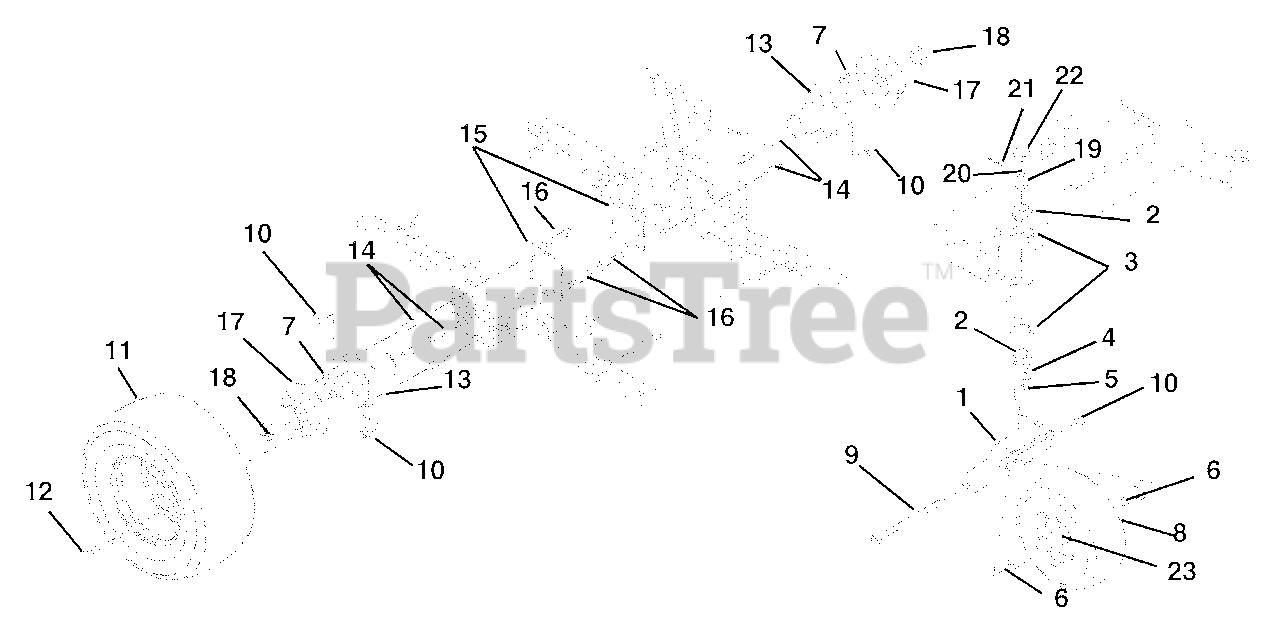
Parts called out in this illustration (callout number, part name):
1	FORK - BLACK
2	BRG, CONE W/ GREASE
3	BRG-CUP1.980X.420
4	BEARING SEAL 1.5 X 2 X .18
5	SPACER 1.005X1.5075X.375
6	SPACER, WHEEL
7	KEY-WDRF .31X1.00 SFT #B
8	WHEEL/TIRE ASM
9	@BLT-HEX .50-13X9.00 GR5 YWZC
10	@NUT-LK-TOP-FLG .50-13 YWZC
11	TIRE/WHEEL ASSY, 23X10.50-12
12	BLT, LUG .50-20 X 1.38
13	WHEEL MOTOR, MB15
14	BSHG-SLV .513X.748X2.129
15	PLATE, MOTOR SUPPORT
16	BOLT, WHEEL MOTOR 1/2-13X5.00
17	HUB & DISK (PARK) 8" 1/2 HOLE
18	NUT-LK-JAM-PTCH 1.00-20
19	WSHR-FL-STL.755X1.375X.062YWZC
20	NUT, SLOTTED .75-16
21	@PIN-CTR .16X1.00 EXTPRSQCT YZ
22	CAP,DUST
23	BRG, 25MM ID X 52MM OD X 15MM
